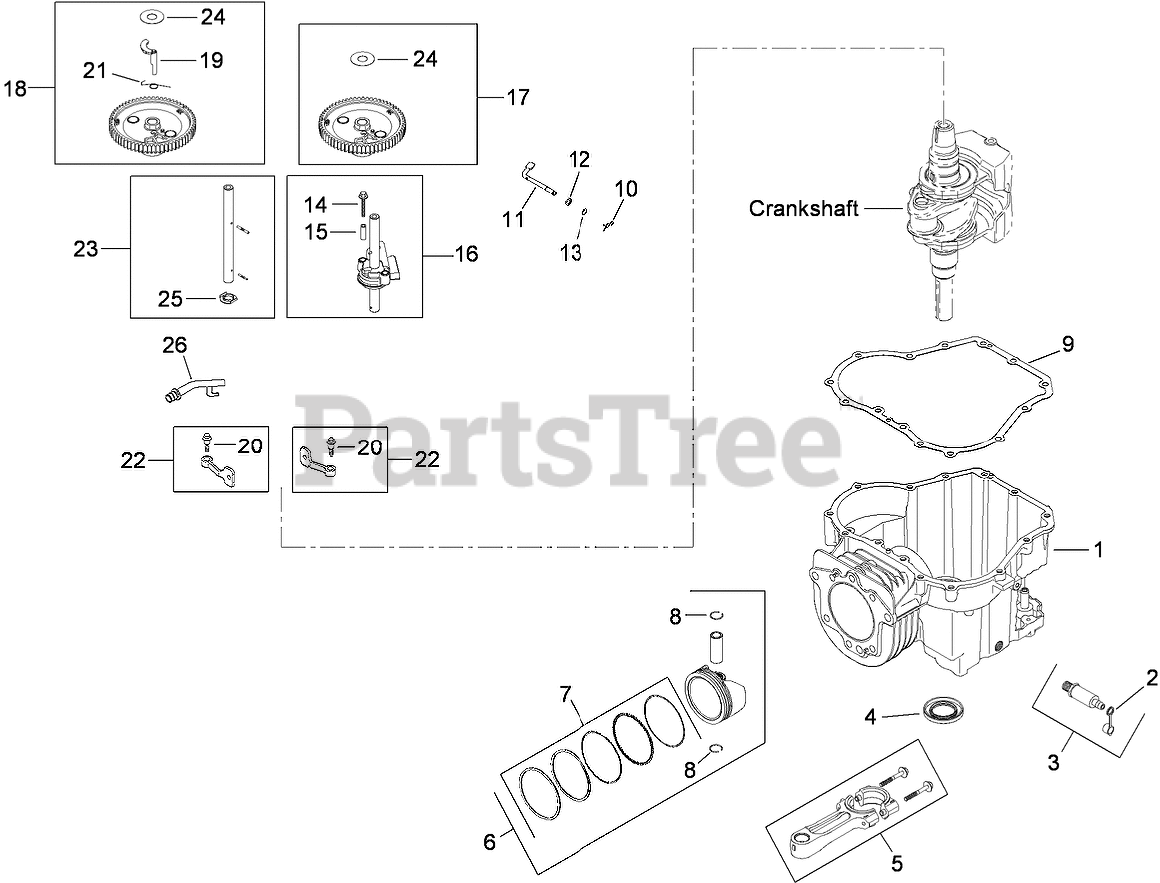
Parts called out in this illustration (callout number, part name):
1	SV610/620 SHORT BLOCK
2	CAP-VALVE, OIL DRAIN
3	OIL DRAIN VALVE KIT (INCLUDES REF 2)
4	Seal-Oil
5	CONNECTING ROD ASM
6	PISTON W/RING SET (94MM) (INCLUDES REF 7, 8)
7	RING SET (94MM)
8	RETAINER-PIN, PISTON
9	Gasket-Plate, Closure
10	Clip-Pin, Hitch
11	Shaft-Cross, Governor
12	WASHER-FLAT (6mm)
13	WASHER-FLAT (1/4)
14	Screw-Pump, Oil
15	Spacer-Screw, Oil Pump
16	OIL PUMP ASM (INCLUDES REF 14, 15)
17	CAM GEAR ASM (INTAKE)) (INCLUDES REF 24)
18	CAM GEAR ASM (EXHAUST) (INCLUDES REF 19, 21, 24)
19	WEIGHT-ACR
20	Bolt-Shoulder (M6x1x26)
21	Spring-A C R
22	Cam Lever ASM (INCLUDES REF 20)
23	CAMSHAFT CENTER ASM (EXHAUST) (INCLUDES REF 25)
24	Washer-Thrust, A C R
25	WASHER-THRUST
26	Tube-Back, Drain
